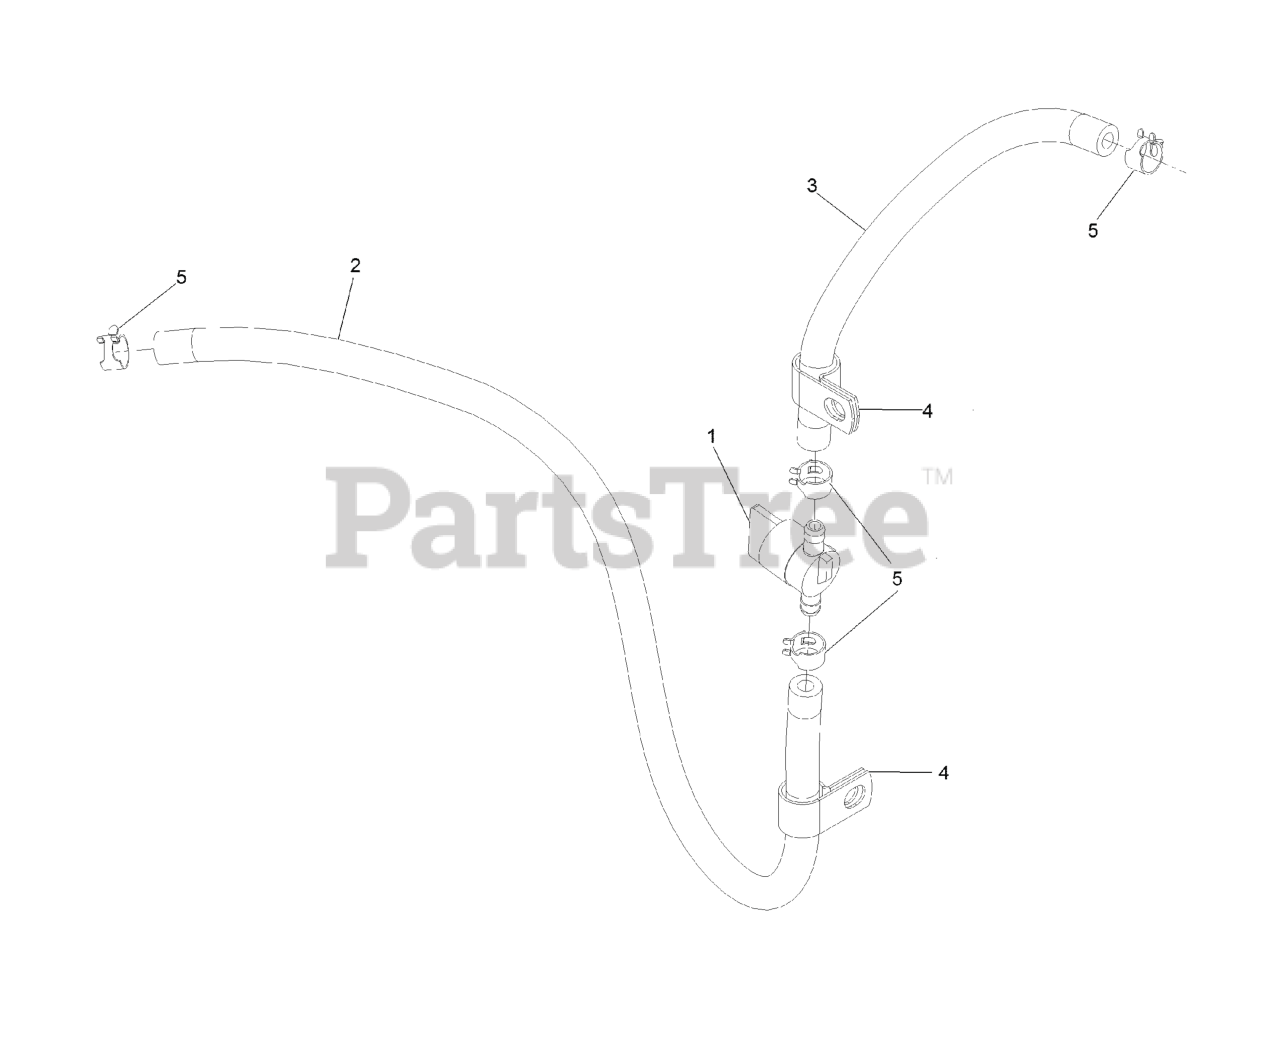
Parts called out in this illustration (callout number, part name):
1	VALVE-FUEL
2	HOSE-FUEL
3	HOSE-FUEL
4	CLAMP-R
5	CLAMP-HOSE
